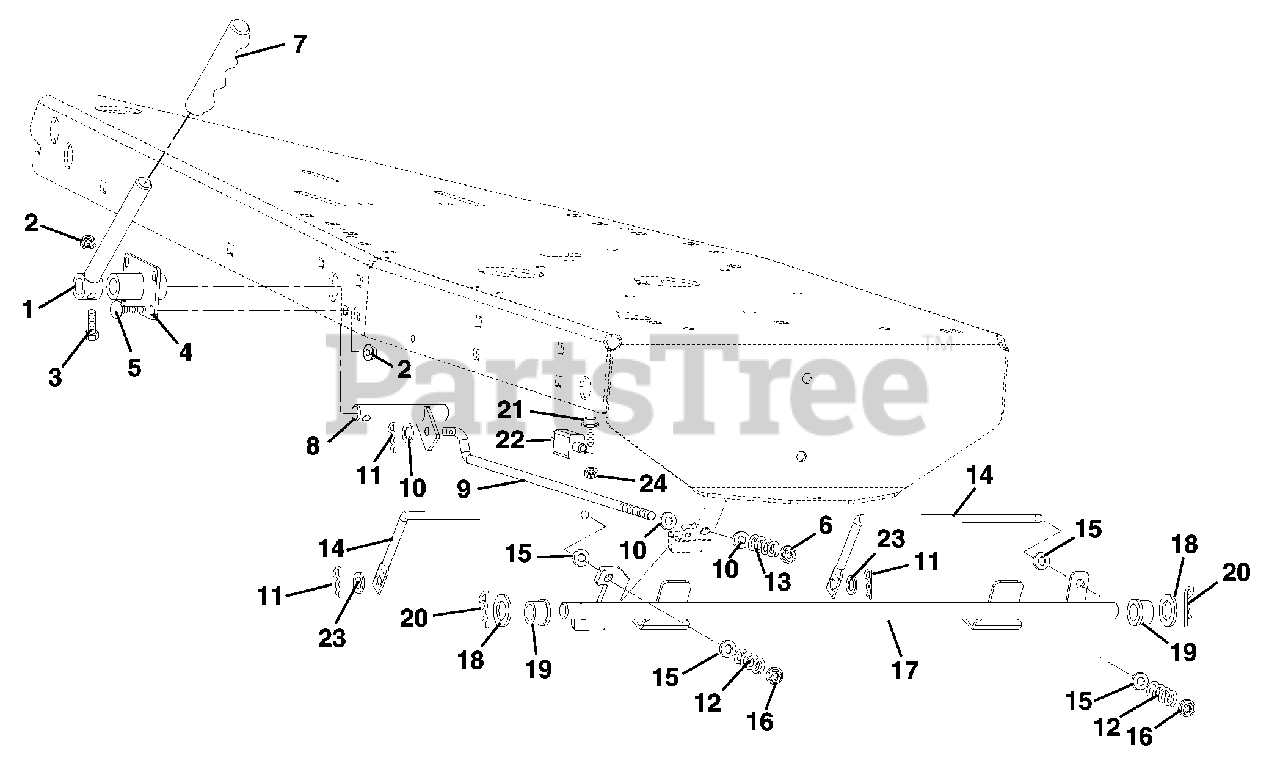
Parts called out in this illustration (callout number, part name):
1	WMT, HANDLE
2	NUT-LK-TOP-FLG .31-18 BLKZC
3	@BLT-HEX .31-18X1.50 GR5 YWZC
4	WMT, HANDLE PIVOT
5	BLT-RDHDSQNK .31-18X.75 G5BZ
6	NUT-LK-TOP-FLG .38-16 BLKZC
8	WMT, PIVOT ARM
9	ROD, ARM-LOCKING
10	@WSHR-FL-STL.406X.812X.065 YWZ
11	PIN-HAIR, ENDRIES #25 YWZC
12	SG-COMP .045X.50X1.187
13	SG-COMP .063X.53X1.187
14	ROD, BRAKE ACTUATING
15	@WSHR-FL-STL.344X.688X.065YWZC
16	@NUT-LK-TOP-FLG .31-18 YWZC
17	SHAFT, BRAKE-WELDMENT
18	WSHR-FL-STL .890X1.500X.1196YZ
19	BSHG-FLG .630X1.000X.625 NY
20	PIN, SPRING CLIP
21	SCR-TAP 10-24X.75 HWH TR YWZC
22	SWITCH- SINGLE POLE N.O.
23	@WSHR-FL-STL.406X.812X.065 YWZ
24	@NUT-LK-NYL 10-24 W/INSRT YWZC
